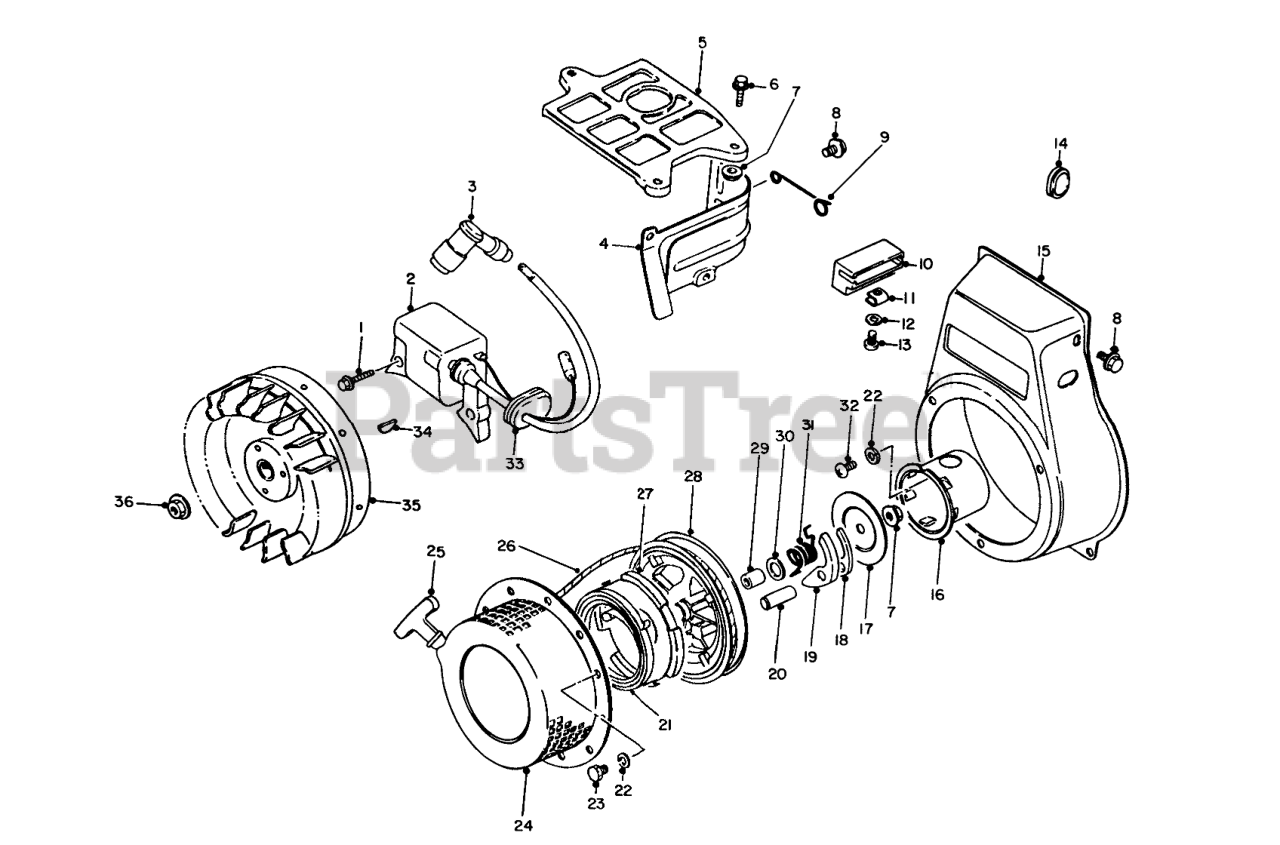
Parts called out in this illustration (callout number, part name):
2	Coil-Primary
3	SPARK PLUG CAP
4	Cowling-Side
5	Cowling-Upper
9	CLAMP
10	Holder-Lead Connector
12	Washer
14	Plug-High Tension Cord Hole
15	Cover-Cooling Fan
16	Pulley-Starter
17	Plate
18	Ratchet
19	Ratchet
21	SPRING
22	LOCKWASHER
24	Starter Assembly-Recoil (Incl. Ref. #7, 17-23 & 25-31)
25	Grip Assembly (Incl. Ref. #26)
26	Rope
27	SPRING CASE
29	Cover
30	Plate-Slide
31	Spring
32	Screw
33	Grommet
35	Flywheel
36	Nut
